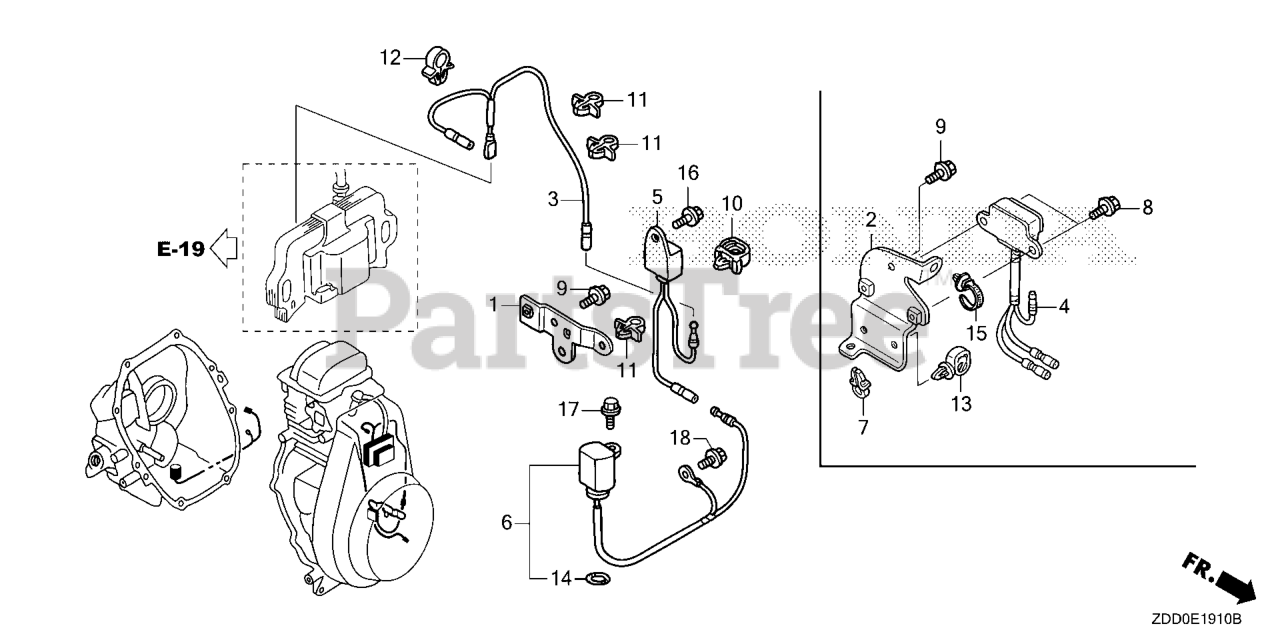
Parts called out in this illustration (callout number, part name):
2	BRACKET, OIL ALERT UNIT
3	WIRE, STOP SWITCH
4	ALERT UNIT, OIL (START LED)
6	SWITCH ASSY., OIL LEVEL
7	HOLDER, STOP SWITCH WIRE Use up to Engine SN 2056819.
8	BOLT, FLANGE (5X8)
9	BOLT, FLANGE (6X14)
11	CLIP, CABLE (A)
12	CLIP B, CABLE
13	CLIP, WIRE HARNESS (25MM)
14	O-RING (11.8X2.4)
15	CLIP, HARNESS BAND (151.5MM) (NATURAL)
17	BOLT, FLANGE (6X14)
18	BOLT, FLANGE (6X12) (CT200)
18	BOLT, FLANGE (6X14)
